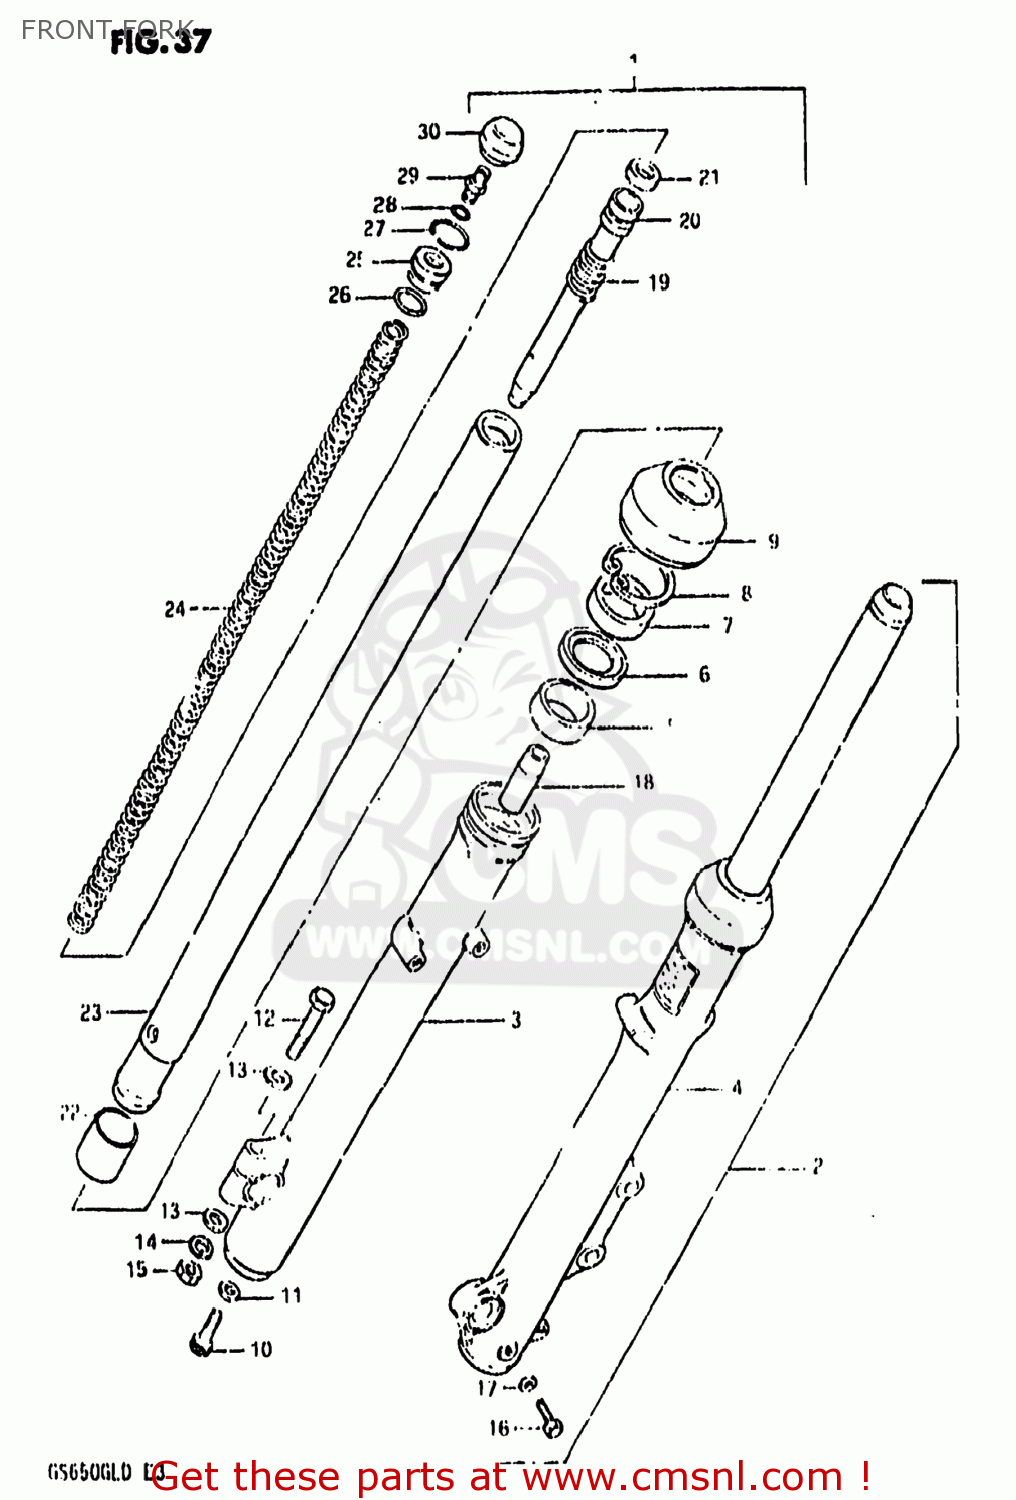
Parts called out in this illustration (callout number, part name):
1	DAMPER ASSEMBLY,RIGHT
2	DAMPER ASSEMBLY,FRONT FORK,LEFT
3	TUBE,FORK,OUTER,RIGHT
4	TUBE,OUTER,LEFT
5	BUSH,GUIDE
6	SPACER,SEAL
7	OIL SEAL,FRONT FORK
8	CIRCLIP,FORK OIL SEAL
9	BOOT
10	BOLT(8X27)
11	GASKET (NAS)
12	BOLT 8X50
13	WASHER
14	LOCK WASHER
15	NUT
16	BOLT
17	GASKET,DRAIN,PLUG (NAS)
18	PIECE,OIL LOCK
19	SPRING,FORK REBOUND
20	CYLINDER,FRONT FORK
21	RING
22	PISTON
23	TUBE,FORK,INNER
24	SPRING,FRONT
25	SEAT,SPRING
26	O-RING
27	RING,STOPPER
28	O-RING
29	VALVE,AIR
30	CAP
